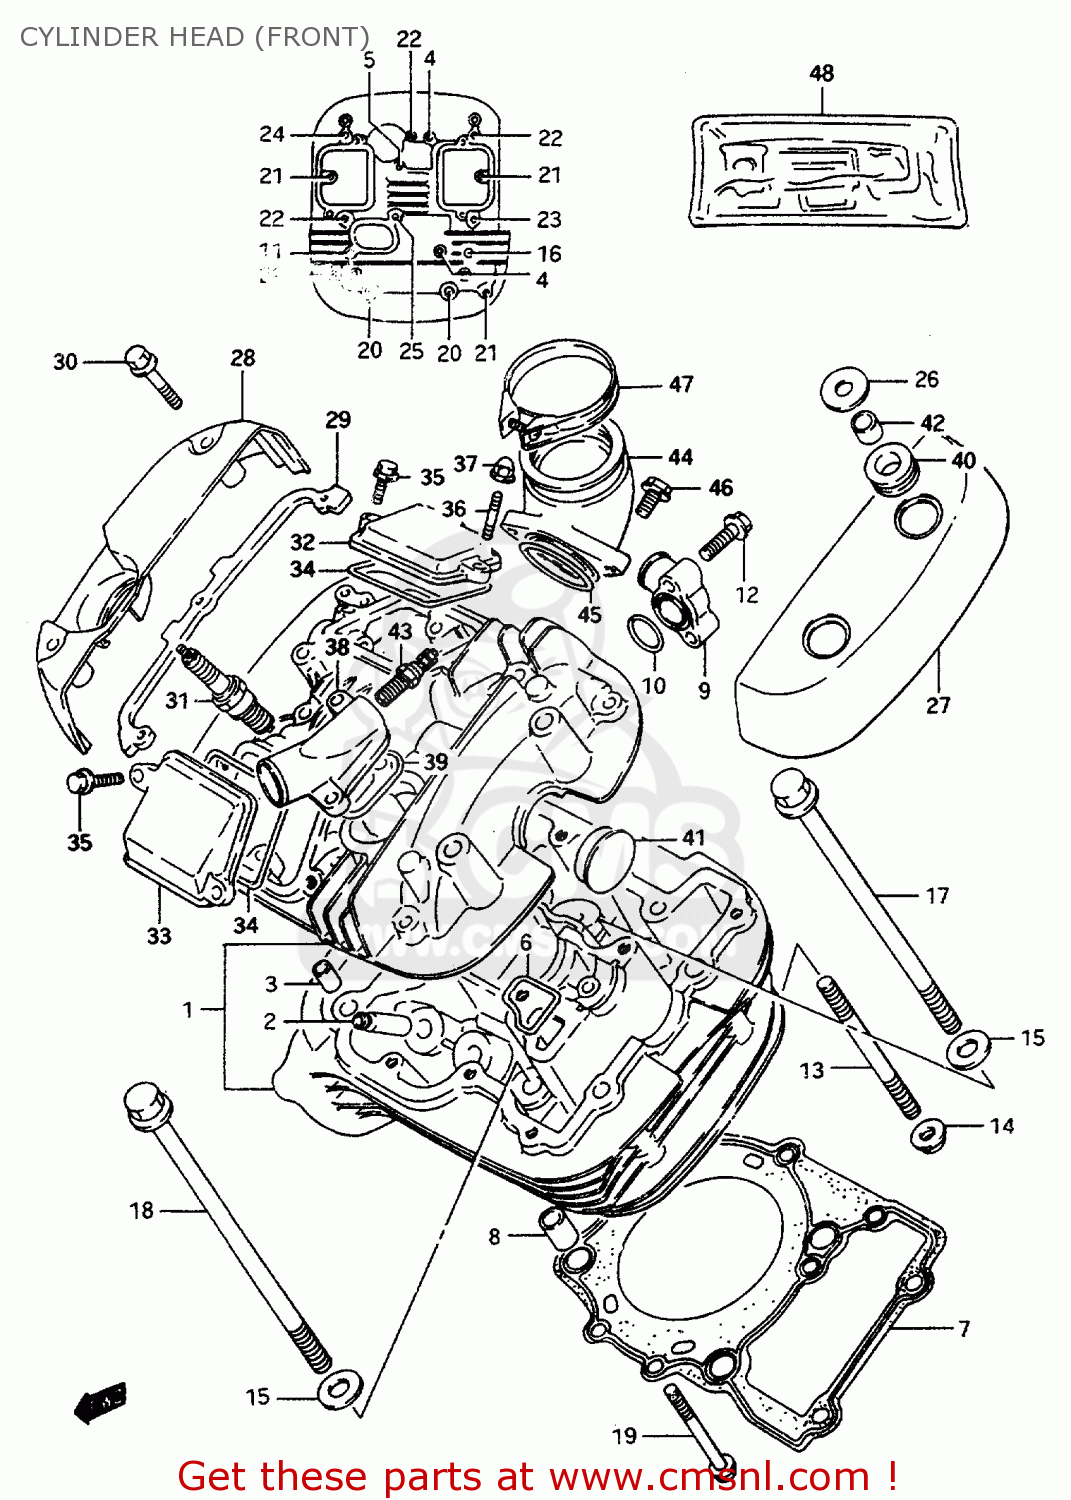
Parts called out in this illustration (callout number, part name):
1	HEAD ASSY, CYLINDER FRONT
2	GUIDE,VALVE
3	PIN(8.4X11X14)
4	BOLT(6X50)
5	BOLT(6X55)
6	GASKET,CYLINDER HEAD WATER (NAS)
7	GASKET,CYLINDER HEAD FR (MCA)
8	PIN
9	UNION,CYLINDER HEAD WATER
10	O RING(D:2.4,ID:17.8)
11	BOLT
12	BOLT
13	BOLT,STUD
14	NUT
15	WASHER (10.5X22X2.3)
16	BOLT(8X140)
17	BOLT(10X155)
18	BOLT(10X165)
19	BOLT
20	BOLT(8X245)
21	BOLT
22	BOLT
23	BOLT
24	BOLT
25	BOLT(6X55)
26	WASHER (8.2X24X1.6)
27	CAP,CYLINDER HEAD COVER FR,L
28	CAP,CYLINDER HEAD COVER FR,R
29	CUSHION,FR,R CAP
30	BOLT
31	PLUG,SPARK(DPR8EA-9)
32	CAP,INSP.INT
33	CAP,INSPECTION,EXHAUST
34	GASKET,INSPECTION CAP (NAS)
35	BOLT
36	STUD 6X16
37	NUT
38	UNION,WATER OUTLET
39	GASKET,WATER OUTLET UNION (NAS)
40	CUSHION
41	PLUG(OD:30)
42	BUSH
43	GAUGE ASSY,WATER TEMP
44	PIPE,INTAKE FR
45	O-RING (D:2.4 ID:39.7)
46	BOLT
47	CLAMP
48	GASKET SET
